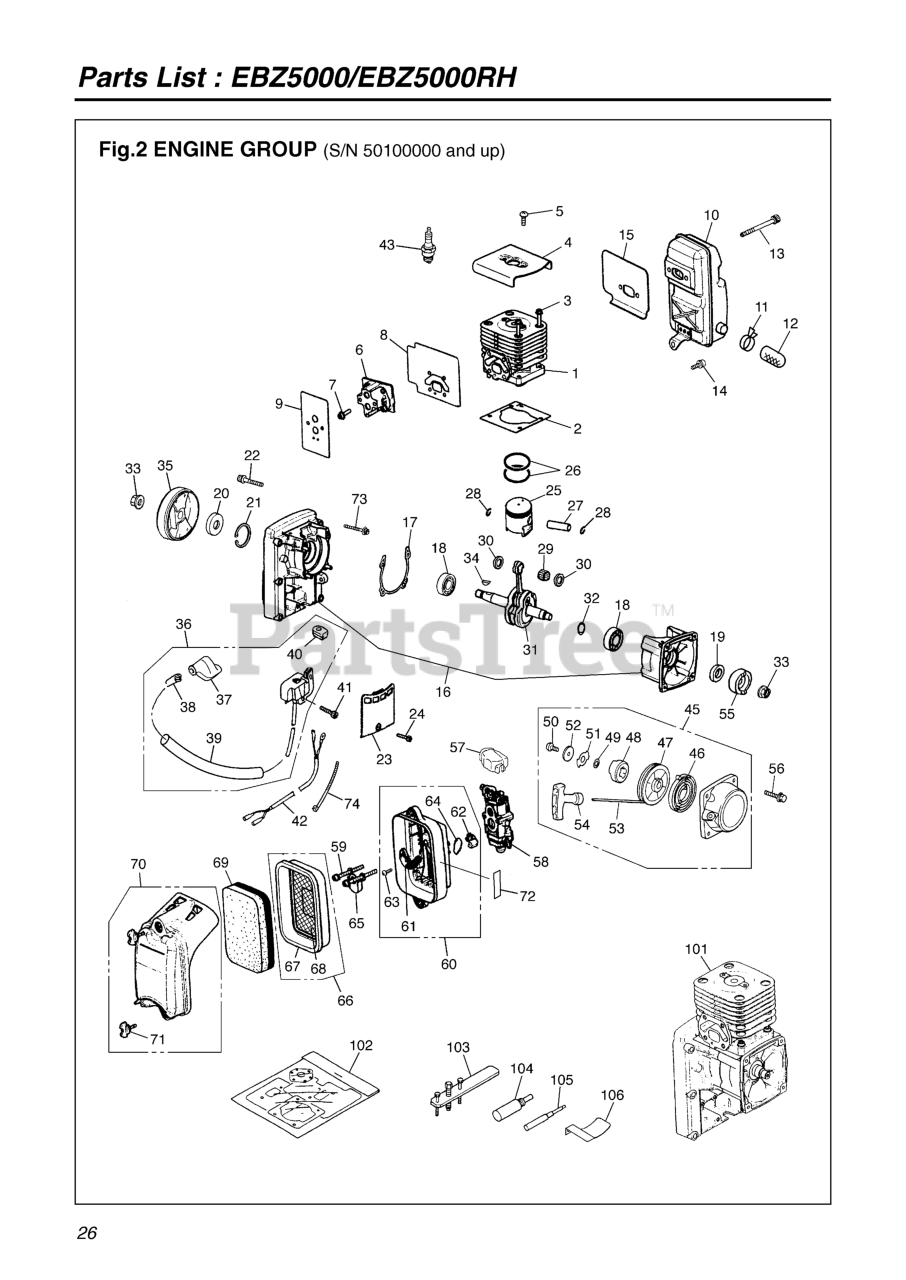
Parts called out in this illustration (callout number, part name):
1	CYLINDER
2	GASKET, BASE
3	BOLT
4	PLATE, CYLINDER
5	SCREW TORX
6	INSULATOR
7	BOLT TORX
8	GASKET (RPLS T1108-13120)
9	GASKET, CARBURETOR
10	MUFFLER
11	ARRESTER
13	BOLT
14	BOLT
15	GASKET, MUFFLER
16	CRANKCASE-C
17	GASKET, CASE
18	BEARING (REPLACES 2810-21240)
19	SEAL, OIL 15 X 25 X 7
20	SEAL (REPLACES 1400-21220)
21	RING, SNAP, M35 X 1.5
22	BOLT
23	COVER
24	BOLT TORX
25	PISTON
26	RING, PISTON (REPLACES -41210)
27	PIN, PISTON
28	RING, SNAP
29	BEARING
30	WASHER (RPLS 1491-41510)
31	CRANKSHAFT COMP
32	SHIM (REPLACES 848-870-G000)
33	NUT, M10
34	KEY
35	ROTOR
36	COIL ASSY.
37	CAP
38	SPRING
39	TUBE
40	GROMMET
41	BOLT TORX
42	CORD-C
45	RECOIL ASSY
46	SPRING (RPLS -75220)
47	REEL
48	DOG
49	WASHER
50	SCREW
51	RETAINER (RPLS 1861-75161)
52	WASHER
53	ROPE
54	KNOB
55	PULLEY (RPLS -75210)
56	SCREW TORX
57	COVER
58	CARBURETOR (WYA 24A)
59	BOLT
60	BODY-A
61	PLATE,CHOKE
62	LEVER
64	RING,O
65	PLATE
66	PACKING-C
67	PACKING
69	ELEMENT
70	COVER-A
71	KNOB
72	LABEL, CHOKE
73	BOLT
101	SHORT BLOCK
102	GASKET KIT
103	PULLER ASSY
104	STOPPER (TOOL)
105	PULLER, PISTON PIN
